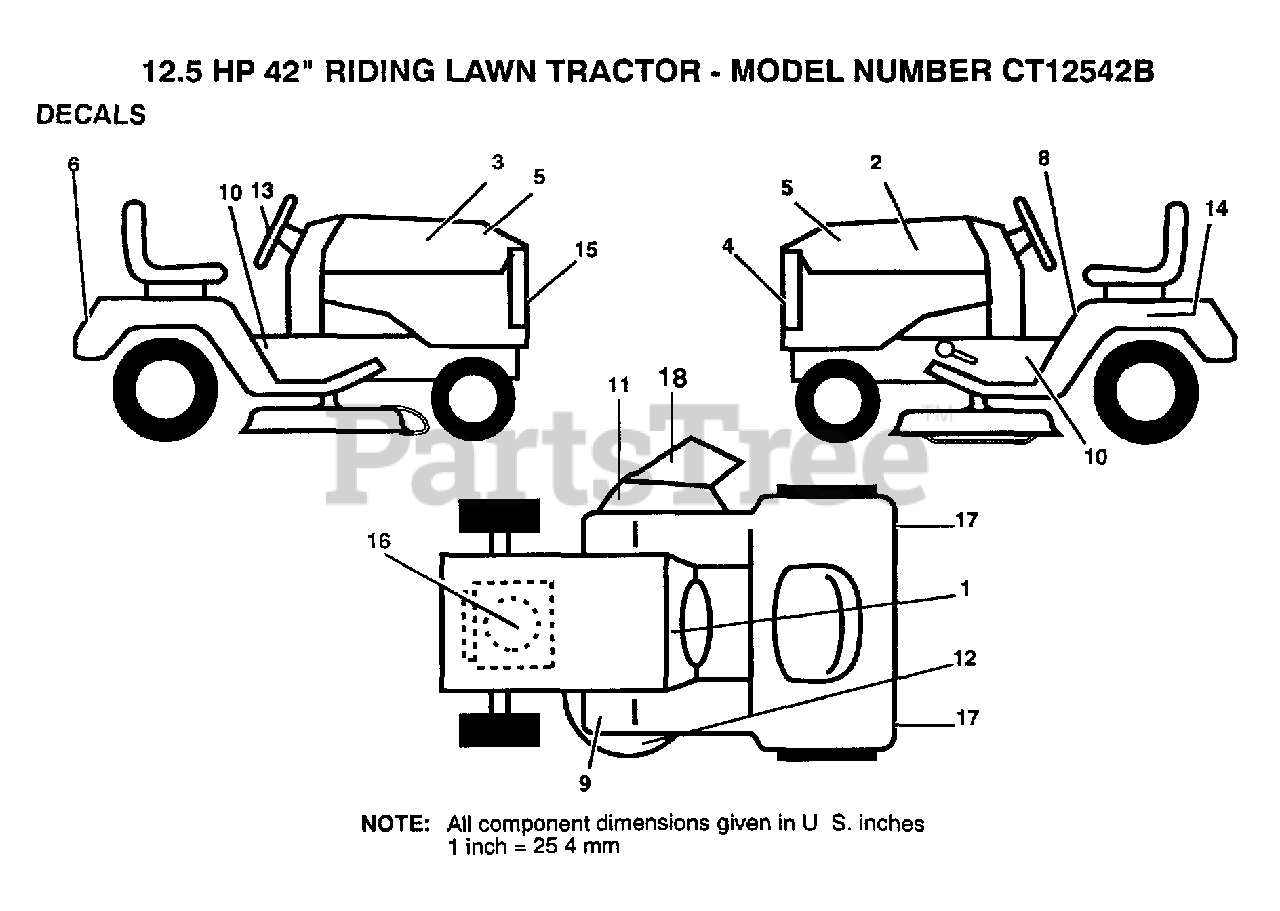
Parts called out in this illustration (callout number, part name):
4	GRILL DECAL
5	"DECAL,HOOD"
6	FENDER DECAL
8	DECAL CAUTION
9	DECAL T
10	CHASSIS DECAL
11	DECAL WARNING
12	DECAL YT
13	"DECAL,STR WHL"
14	DECAL
17	REFLECTOR-TAIL YT
18	DECAL WARNING
